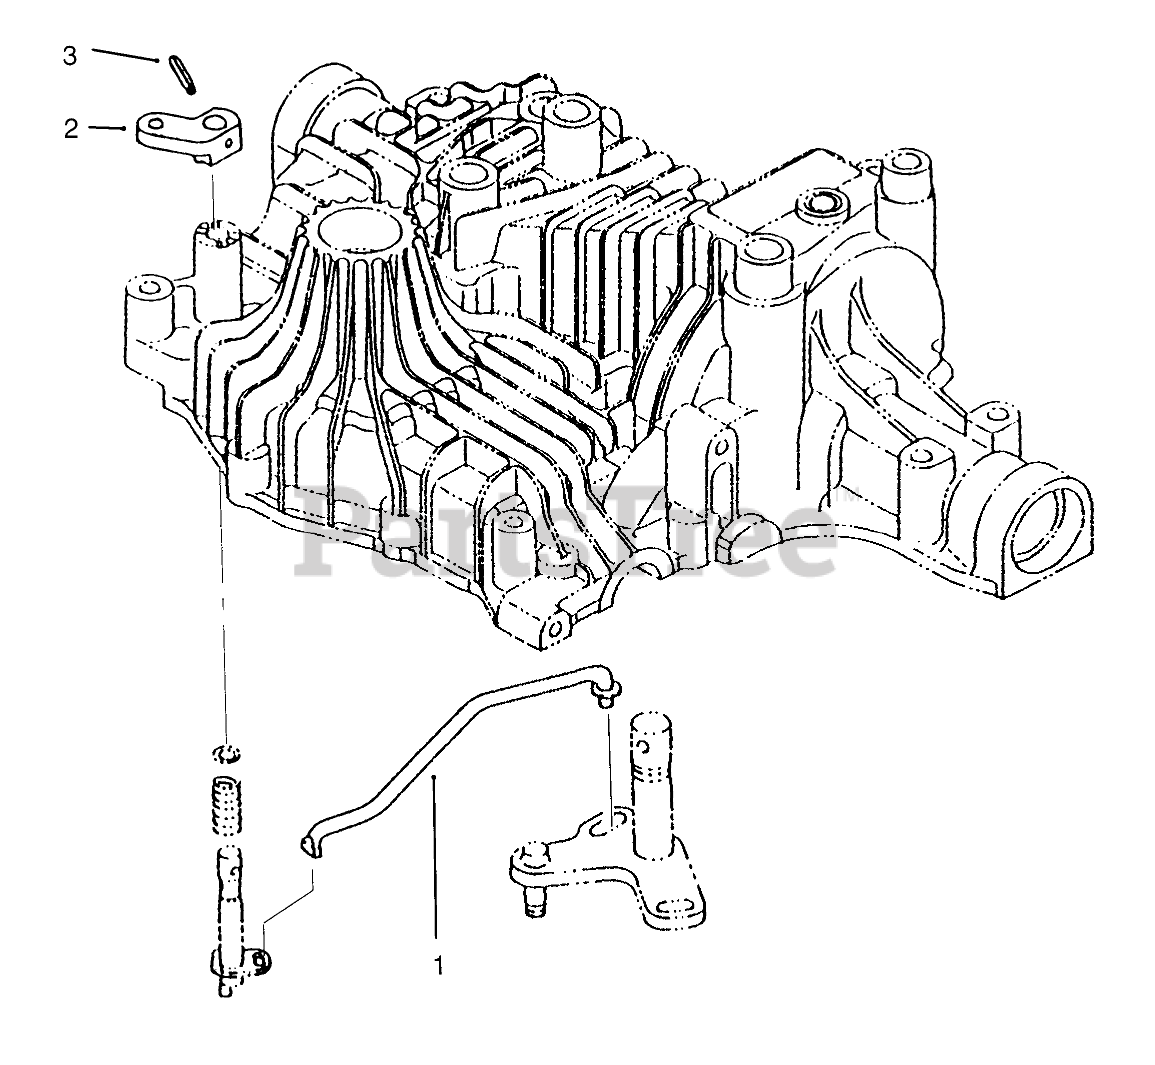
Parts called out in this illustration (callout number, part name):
1	ROD-BYPASS
2	ARM-VALVE RELEASE
3	PIN-ROLL
